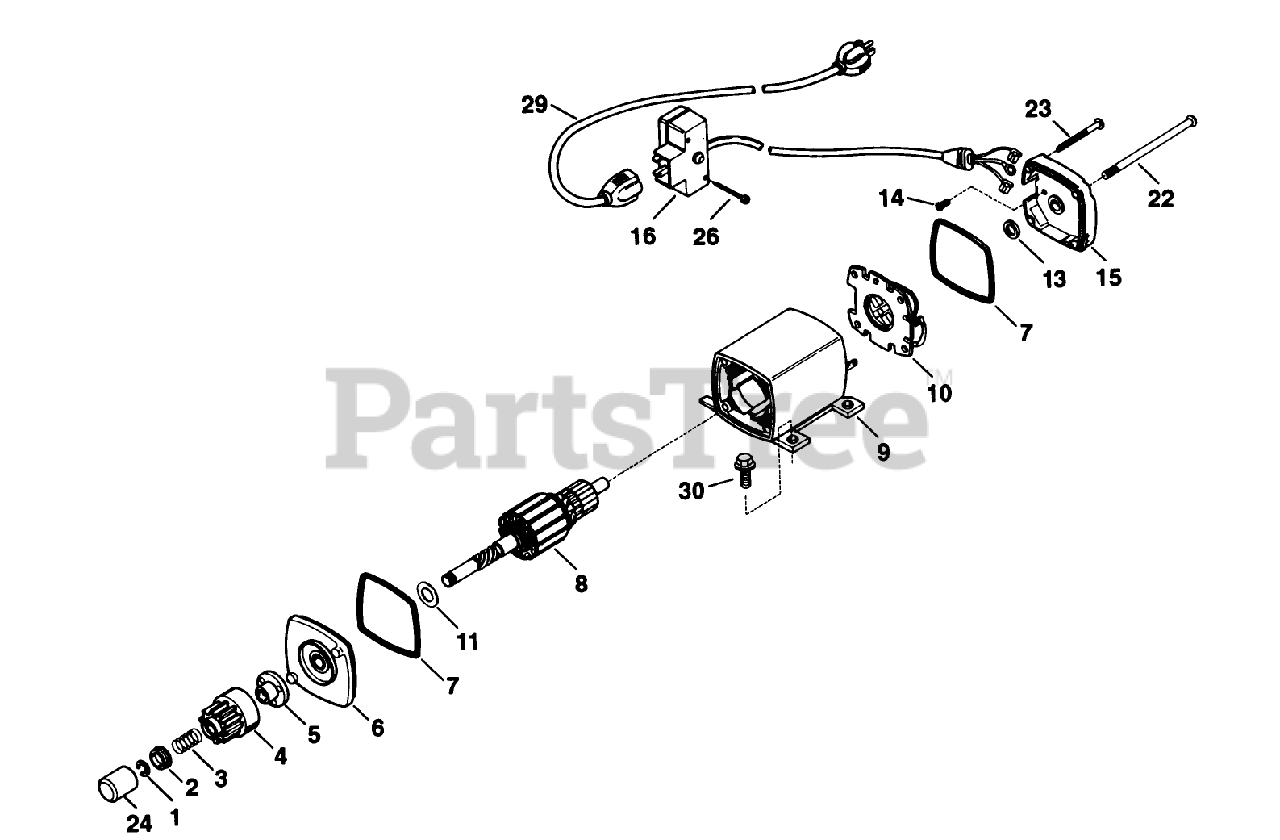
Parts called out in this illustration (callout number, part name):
1	Ring-Retainer
2	Retainer-Spring
3	Spring-Anti Drift
4	Gear
5	Nut Retainer (Incl. Ref. #1)
6	Cap Assembly-Cap End (Incl. Ref. #7)
7	O-Ring
8	Armature
9	Housing Assembly
10	Brush Card ASM
11	Washer-Thrust
13	Washer-Thrust
14	Screw-Ground
15	Cap Assembly (Incl. Ref. #7)
16	Box Assembly-Switch (Incl. Ref. #26)
22	Bolt-Case
23	Screw-Ground
24	Cover-Dust
26	Screw
29	Cord-Extension (10-6)
30	Screw
